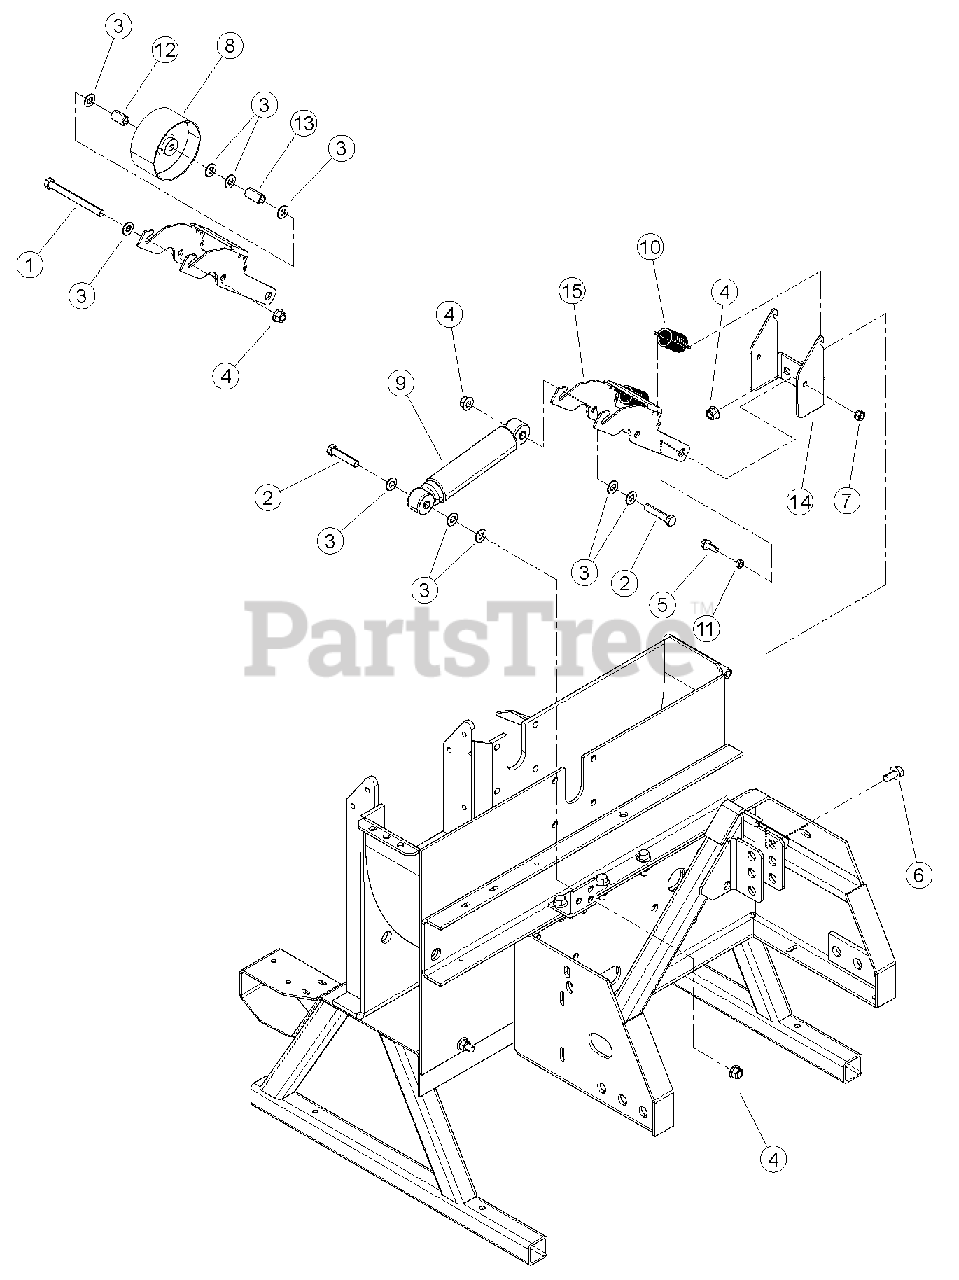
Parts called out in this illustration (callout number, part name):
1	BOLT, 1/2 X 5-1/2 HEX GR5 ZP
2	BOLT, 1/2 X 2-1/2 GR5 HEX CAP ZP
3	WASHER, 1/2" SAE FLAT ZP
4	NUT, 1/2-13 NYLOCK FLANGE
5	BOLT, 3/8 X 1 FLANGE NC
6	BOLT, 1/2 -13 X 1-1/4 FLANGE NC
7	NUT, 3/8-16 NYLOCK FLANGE
8	PULLEY, IDLER 5 X 2.50"
9	ABSORBER, IDLER SHOCK
10	SPRING, 1.25 OD X 3.50 LG X .148 WD
11	SPACER, IDLER PIVOT
12	SPACER, .75 X 1.18
13	SPACER, .75 X 1.47
14	BRACKET, INSIDE IDLER MOUNTING
15	ARM, INSIDE IDLER
